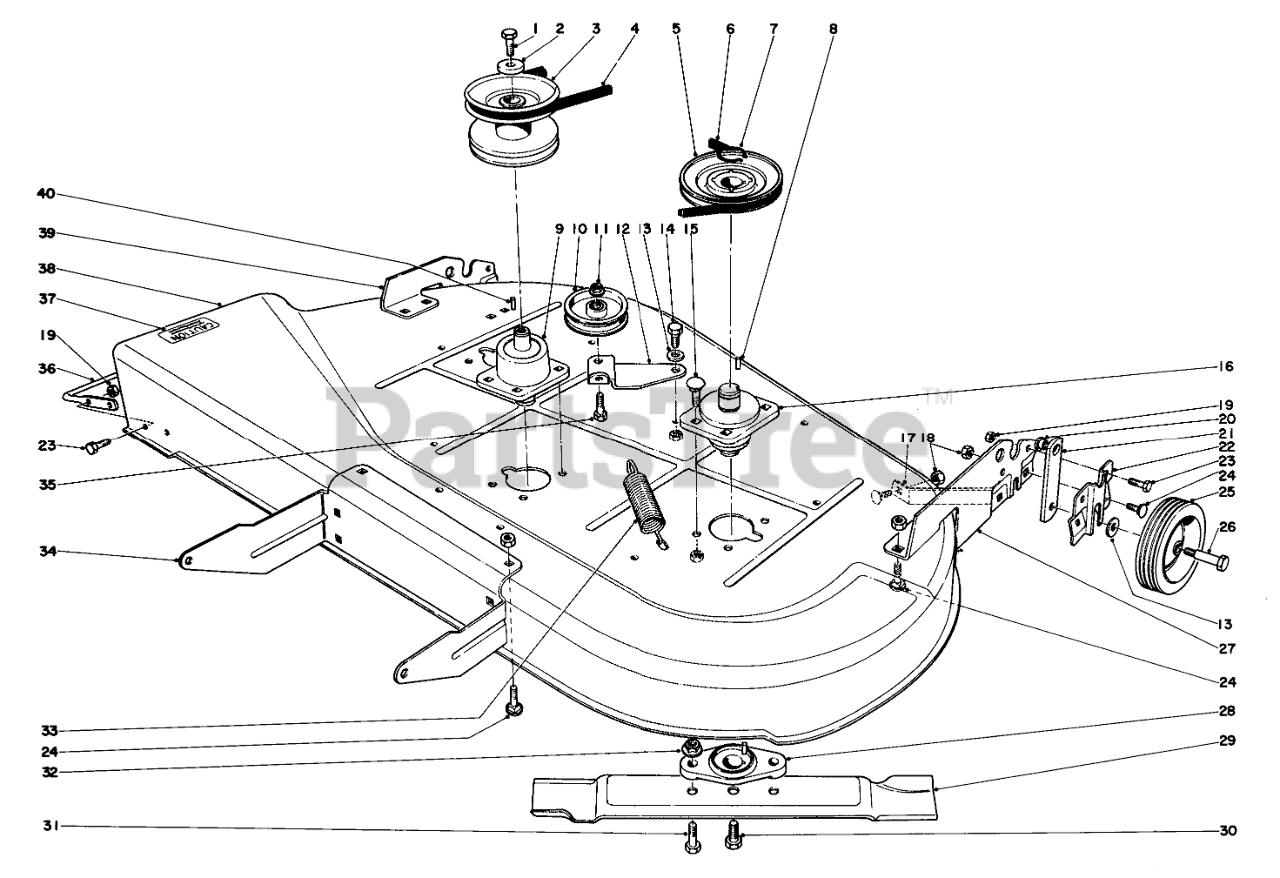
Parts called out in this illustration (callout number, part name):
1	Lockscrew
2	Washer
3	Sheave
4	V-Belt (Spindle Drive)
5	Sheave
6	V-Belt (Blade Drive)
7	Ring-Snap
8	Key
9	Housing, Idler
10	Flat Idler
11	NUT-HF
12	Idler Lever
13	WASHER-FLAT
14	Screw
15	BOLT-CARR
16	Housing, Blade Shaft
17	Brace, Wheel Bracket
18	Nut
19	NUT-LOCK
20	Bushing
21	Slide Height Adj .
22	Retainer, Height Adj.
23	SCREW-HH
24	SCREW-CARR
25	Wheel
26	Screw
27	Bracket, Wheel L. H.
28	Adapter Blade
29	Blade
30	Capscrew
31	SCREW-HH
32	NUT-HF
33	SPRING IDLER SLIDE
34	Housing Bracket
35	SCREW-HH
36	Foot Guard
37	Decal
38	Housing
39	Bracket, Wheel R.H.
40	KEY-SQUARE
